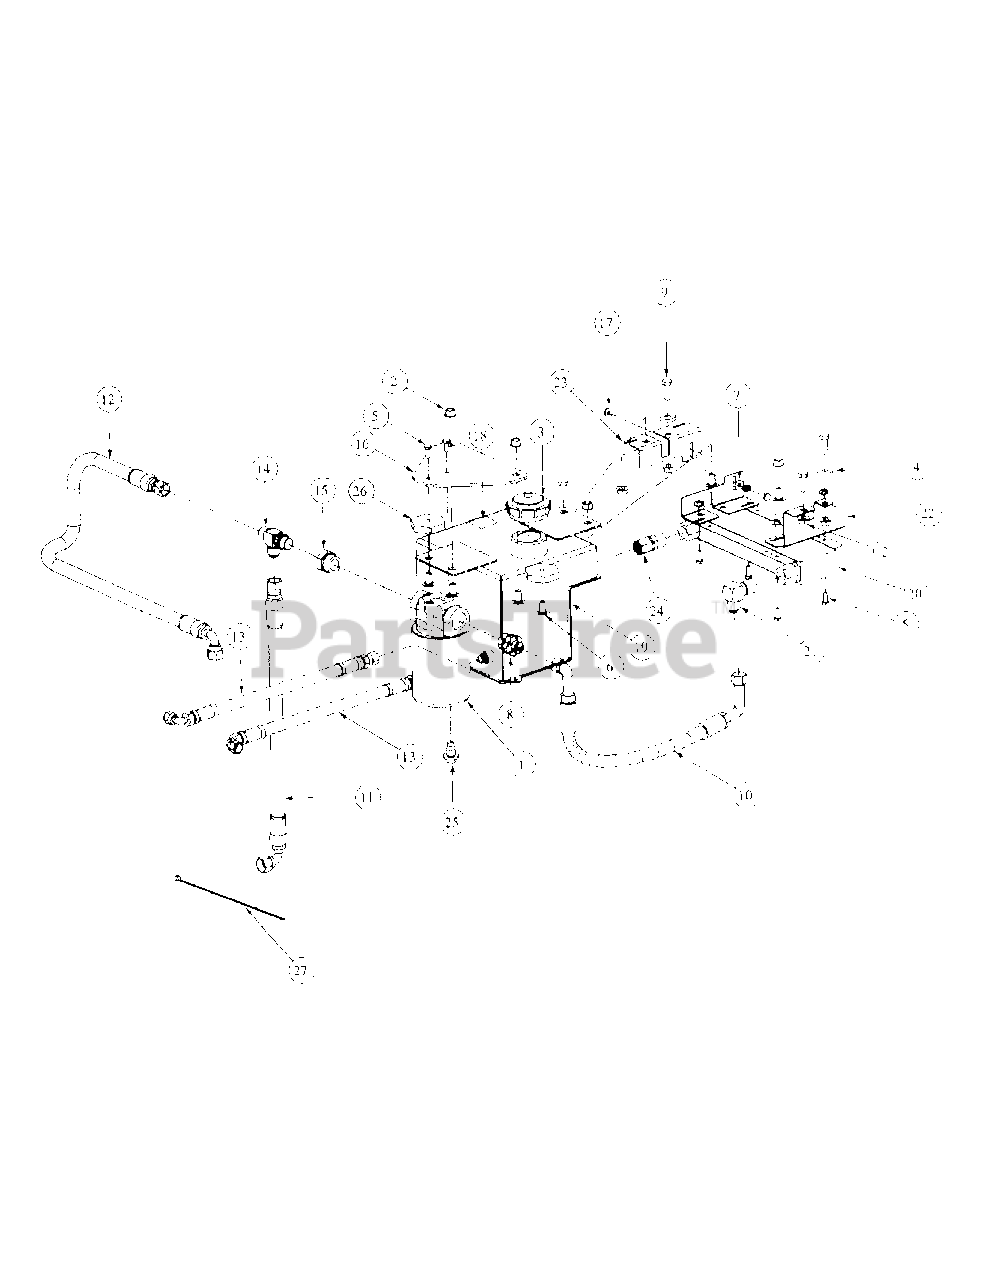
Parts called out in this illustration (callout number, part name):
1	Filter Head 3/4 w/Filter
1	Filter, .33 Micron
2	Hex Nut, 3/8-16, Flange Lock
3	Cap, Hydro Oil Tank
4	Idler Washer
5	HHCS, 1/4-20, .620
6	Carriage Bolt, 3/8-16 x .75 LG.
7	Flat Washer 1/4 x .630 x .0515
8	Straight Connector, 1/2 x 3/4
9	HHCS, 3/8-16, 1.00
10	Hose, Hydraulic, Cooler to Filter
11	Hose, Hydraulic, Filter to LHPU
12	Hose, Hydraulic, Filter to RHPU
13	Hose, Hydraulic, Pump to Tank
14	Tee Fitting, 1/2 x 1/2 x 3/4
15	Adapter, 1/2 x 3/4
16	Mounting Plate, Oil Filter
17	Nut, 1/4-20, Hex Flange Lock
18	Decal, Oil Only 20W50
19	Tank Assembly, Hydraulic
20	Heat Exchanger, 1.5 x 11 x 2.77
21	Elbow Fitting, 1/2 NTPF x 1/2
22	Mounting Bracket, RH Heat Exchanger
23	Mounting Bracket, LH Heat Exchanger
24	Fitting Connector, 1/2 NPTF x 1/2 Swivel
25	Plug, Oil Pan Drain
26	Spacer, 2.0 Hex x .41 Long
27	Cable, Tie, 3/16 x .05 x 7.4
